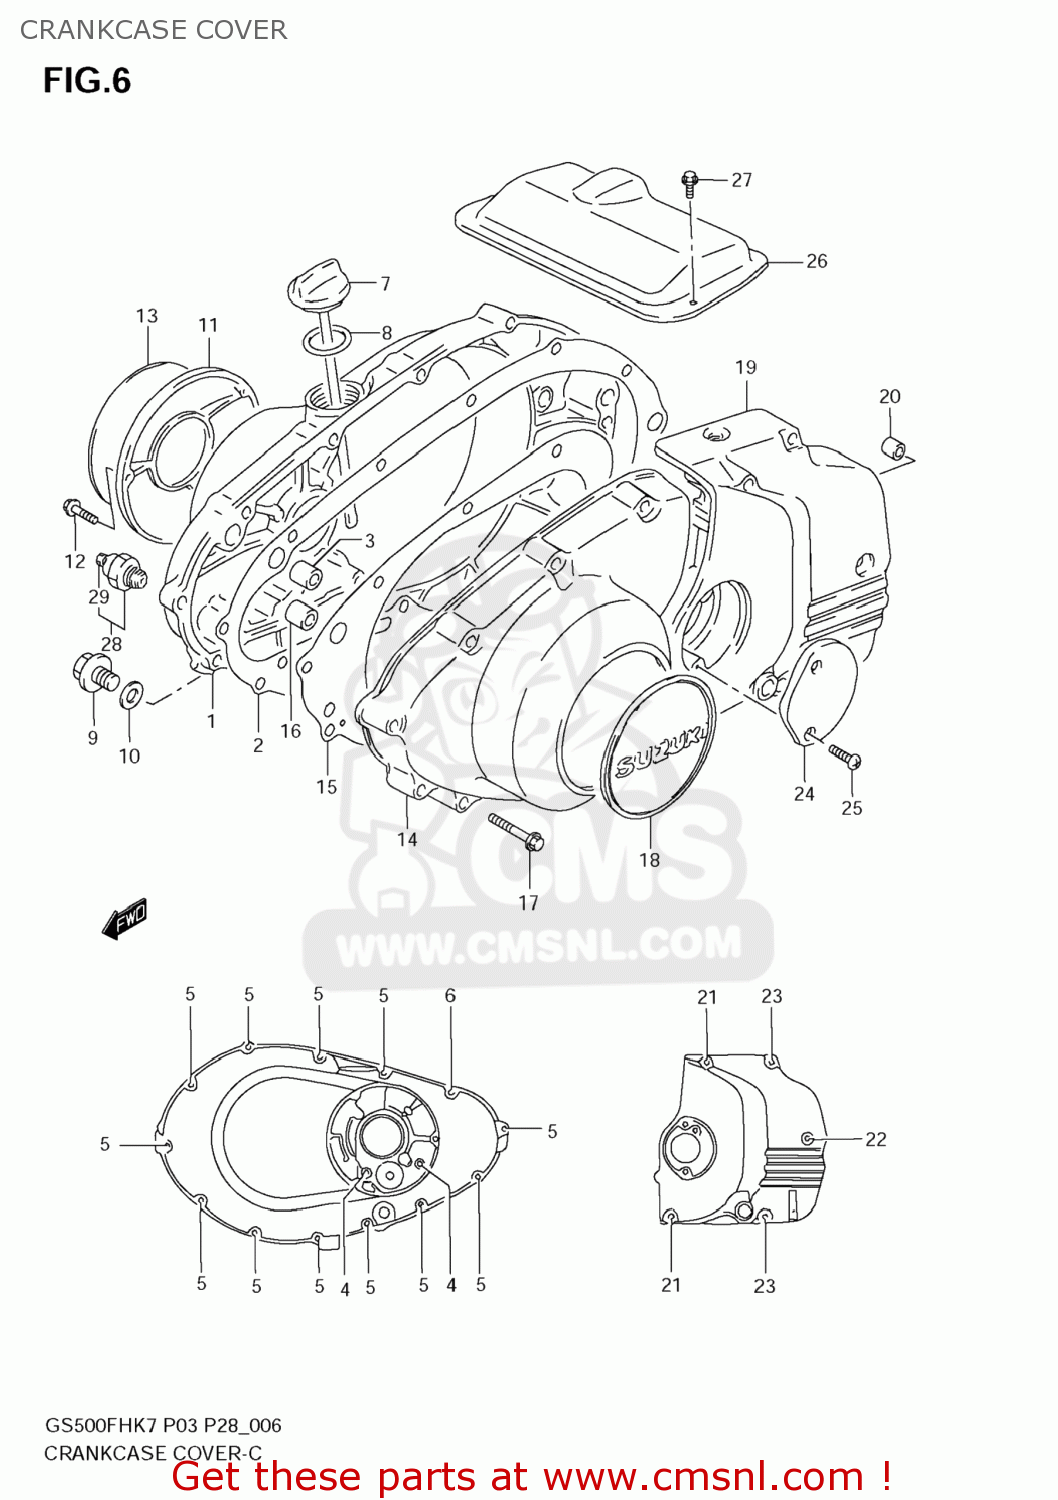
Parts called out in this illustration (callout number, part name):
1	COVER,CLUTCH
2	GASKET,CLUTCH COVER (NAS)
3	PIN
4	BOLT(6X55)
5	BOLT(6X35)
6	BOLT(6X25)
7	GAUGE,OIL LEVEL
8	O RING(D:3.1,ID:26.4)
9	PLUG (14X12)
10	GASKET(13.8X18.8X4.8) (NAS)
11	COVER,CONTACT BREAKER
12	BOLT(5X16)
13	EMBLEM,CONTACT BREAKER COVER
14	COVER,MAGNETO
15	GASKET,MAGNETO COVER (NAS)
16	PIN
17	BOLT(6X35)
18	EMBLEM,CONTACT BREAKER COVER
19	COVER,ENGINE SPROCKET
20	PIN
21	BOLT(6X65)
22	BOLT(6X50)
23	BOLT(6X40)
24	CAP,CLUTCH RELEASE ADJUST
25	SCREW
26	COVER,STARTER MOTOR
27	BOLT
28	SWITCH ASSY,OIL PRESSURE
29	BOLT,OIL PRESSURE SWITCH
